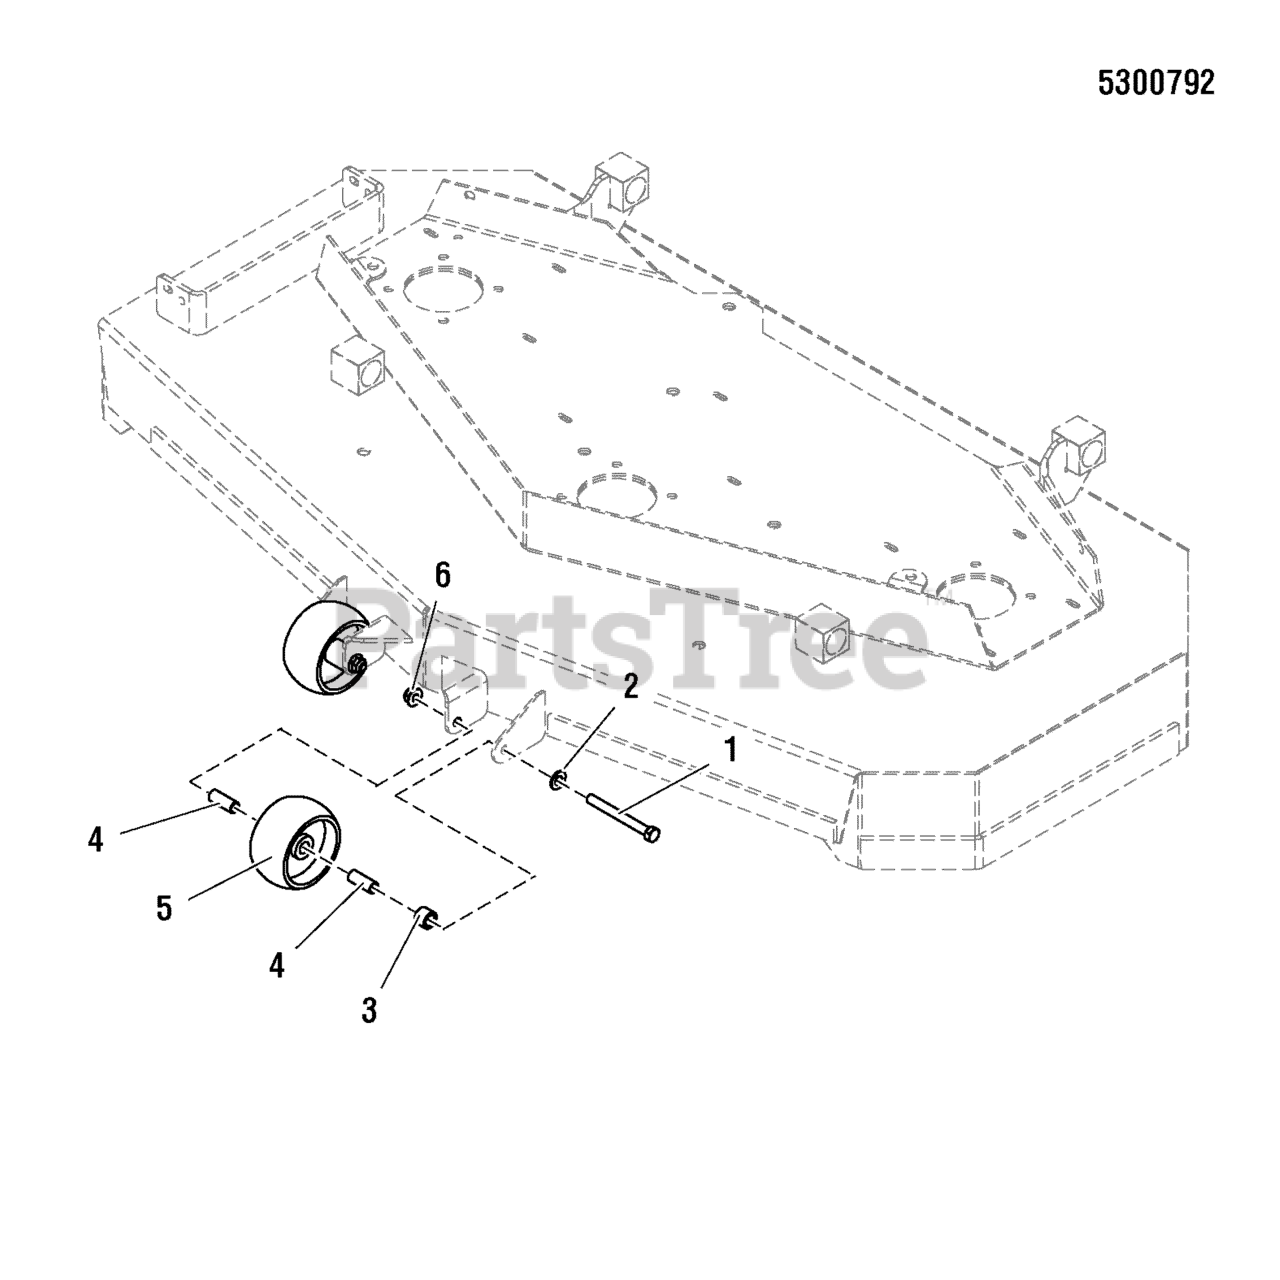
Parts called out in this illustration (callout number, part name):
1	BOLT, 3/8-16 X 3-1/2" GD5 CZ
2	WASHER, 3/8 SAE
3	SPACER, .51 X .75 X .56
4	SPACER, .38 X .50 X 1.25, CZ
5	WHEEL- 2.00 WIDE 3.92 DIA 0.531ID POLY
6	NUT, 3/8-16 HEX NYLOCK FLANGE
